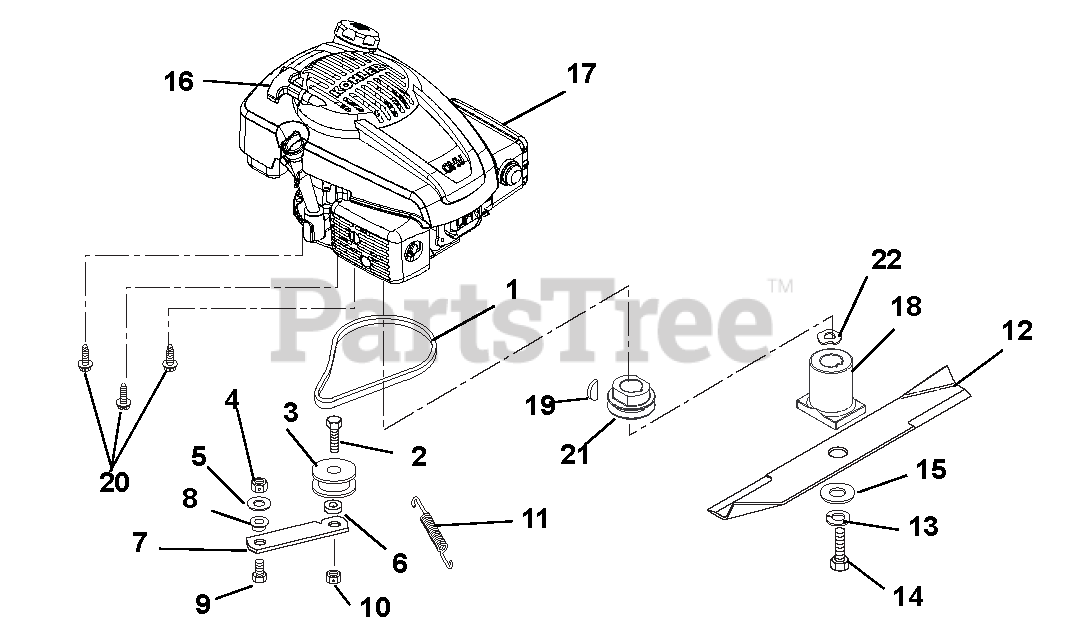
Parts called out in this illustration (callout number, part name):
1	V-BELT, 3L-COGGED
2	@BLT-HEX .44-14X1.50 GR5 YWZC
3	IDLER-FLAT 1.75 X .47
4	@NUT-LK-CTR .31-18 YWZC
5	@WSHR-FL-STL.344X.688X.065YWZC
6	BSHG-SLV .469 X .750 X .430
7	IDLER ARM
8	BSHG-FLG .325X.501X.250X1.120
9	@BLT-HEX .31-18X.75 GR5 YWZC
10	@NUT-LK-CTR .44-14 YWZC
11	SG-TENS .043X.44X3.31 WLD 5.8
12	21" MOWER BLADE
12	BLADE, 21" LM MULCHING
13	@WSHR-LK .38X.094 REG YWZC
14	BOLT, 3/8-24X2.5 G8
15	WSHR-FL-STL .390X1.5X.125 YWZC
16	HANDLE, RECOIL START
17	B&S - 6.5 HP DOV
17	ENGINE, KOHLER XT-7 CE
18	ADAPTER, CE BLADE
19	KEY-WDRF .156X.625X.25 SAE 6
20	@SCR-TAP .38-16X1.00 HWH TR YZ
21	PULLEY-SINTERED IRON LM
22	WASHER-WAVE .885X1.311X.125
